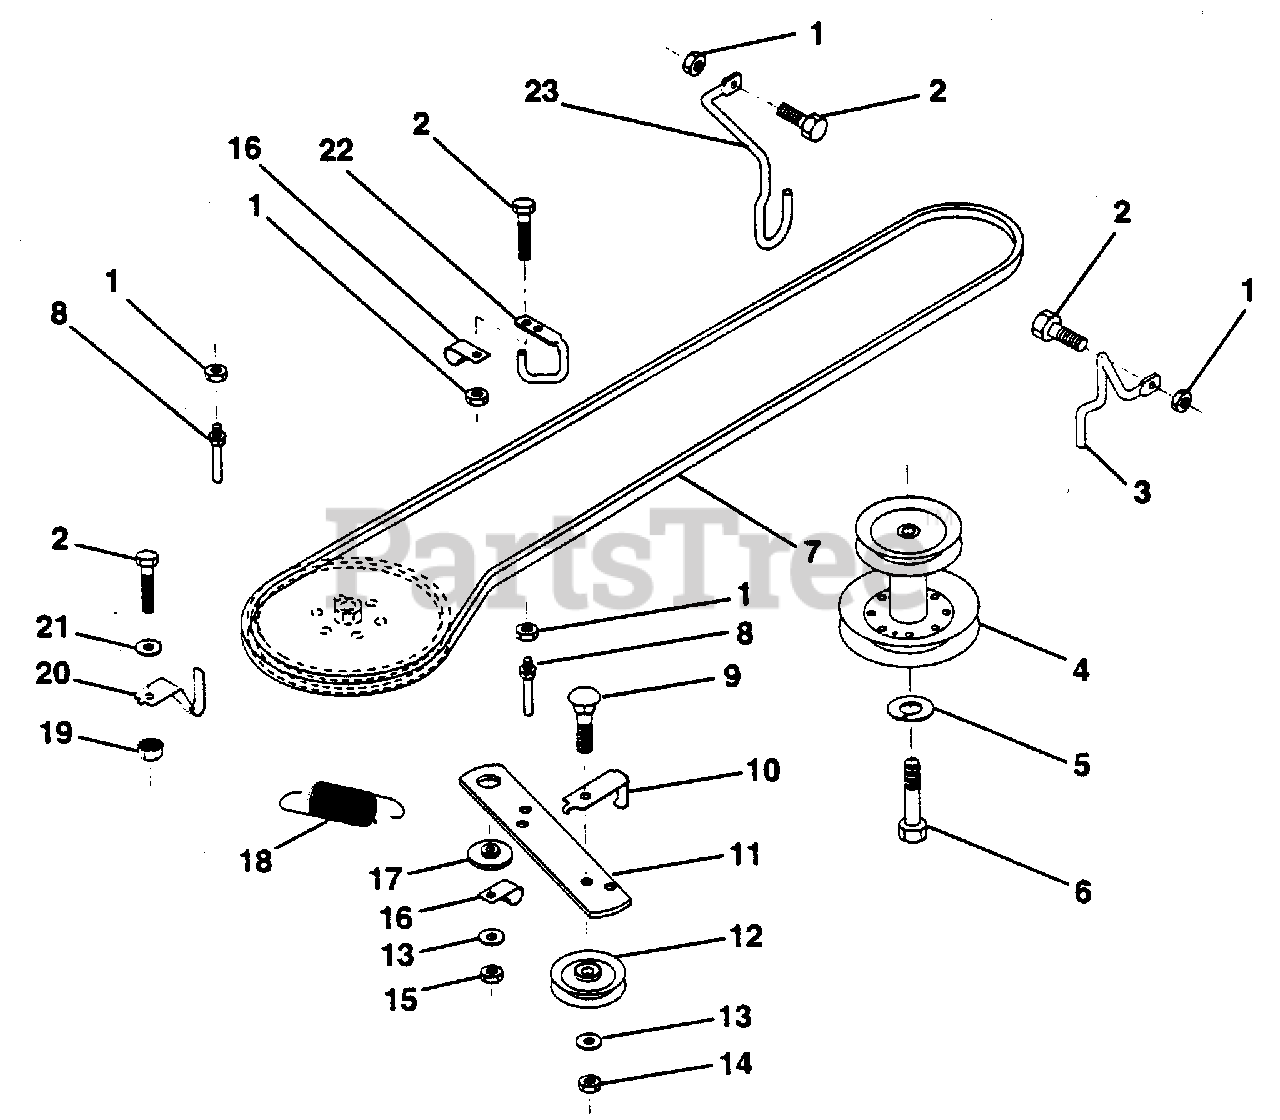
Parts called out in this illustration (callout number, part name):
1	Nut, Lock Hex w/Ins 5/16-18 (AYP part number)
2	Bolt, Hex Head 5/16-18 UNC x 3/4 (AYP part number)
3	Keeper, Mower Drive, R.H. (AYP part number)
4	Pulley, Engine (AYP part number)
5	Washer, Lock 7/16 (AYP part number)
6	Bolt, Hex Hd. 7/16-20 UNF Grade 5 (AYP part number)
7	Traction, V-Belt Drive (AYP part number)
8	Keeper, T/A, Ground Drive Belt (AYP part number)
9	Bolt, Carriage 3/8-16 UNC x 1-1/2 (AYP part number)
10	Keeper, Ground Drive Belt Idler (AYP part number)
11	Arm, Ground Drive Clutch (AYP part number)
12	Idler, Flat (AYP part number)
13	Washer 13/32 x 13/16 x 16 Gauge (AYP part number)
14	Nut, Hex, Centerlock 3/8-16 UNC (AYP part number)
15	Nut, Lock Hex w/Wsh 3/8-16 (AYP part number)
16	Clip, Insulated (AYP part number)
17	Spacer, Retainer (AYP part number)
18	Spring, Extension (AYP part number)
19	Nut, Hex, Keps 5/16-18 UNC (AYP part number)
20	Keeper, T/A, Ground Drive Belt (AYP part number)
21	Washer 11/32 x 5/8 x 16 Gauge (AYP part number)
22	Keeper, Frame Ground Drive Belt (AYP part number)
23	Keeper, Belt LH Front (AYP part number)
